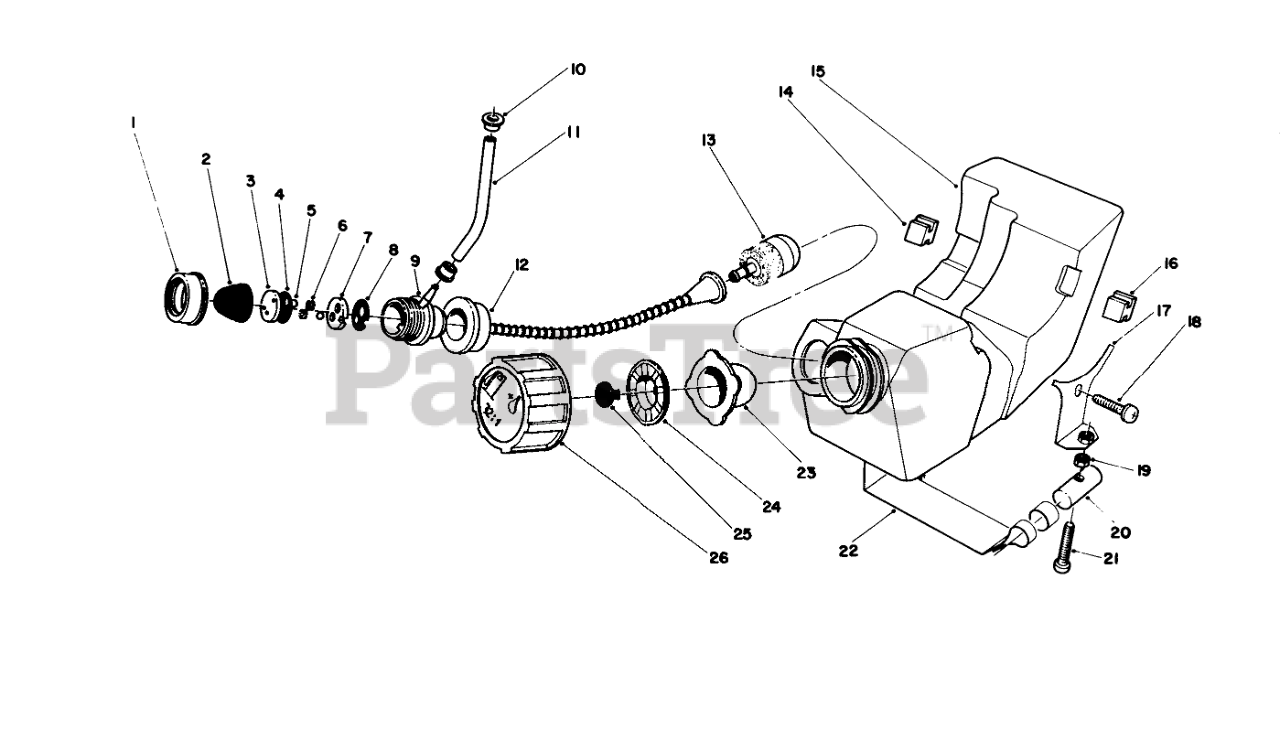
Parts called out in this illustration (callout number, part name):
1	PUMP CAP
3	SEAT VALVE
4	GASKET
6	SPONGE
7	SEAT VALVE
8	GASKET
9	Primer Pump Assembly (Incl.Ref. #1-8)
11	TUBE, FUEL
12	SUCTION HOSE
13	FUEL FILTER
15	Fuel Tank Assembly (Incl.Ref. #1-9, 12, 13, 23-26)
17	Hanger-Tank
18	Screw
21	Screw
22	BAND, TANK
23	GASKET - PACKING
24	HOLDER
25	BREATHER VALVE
26	TANK CAP
